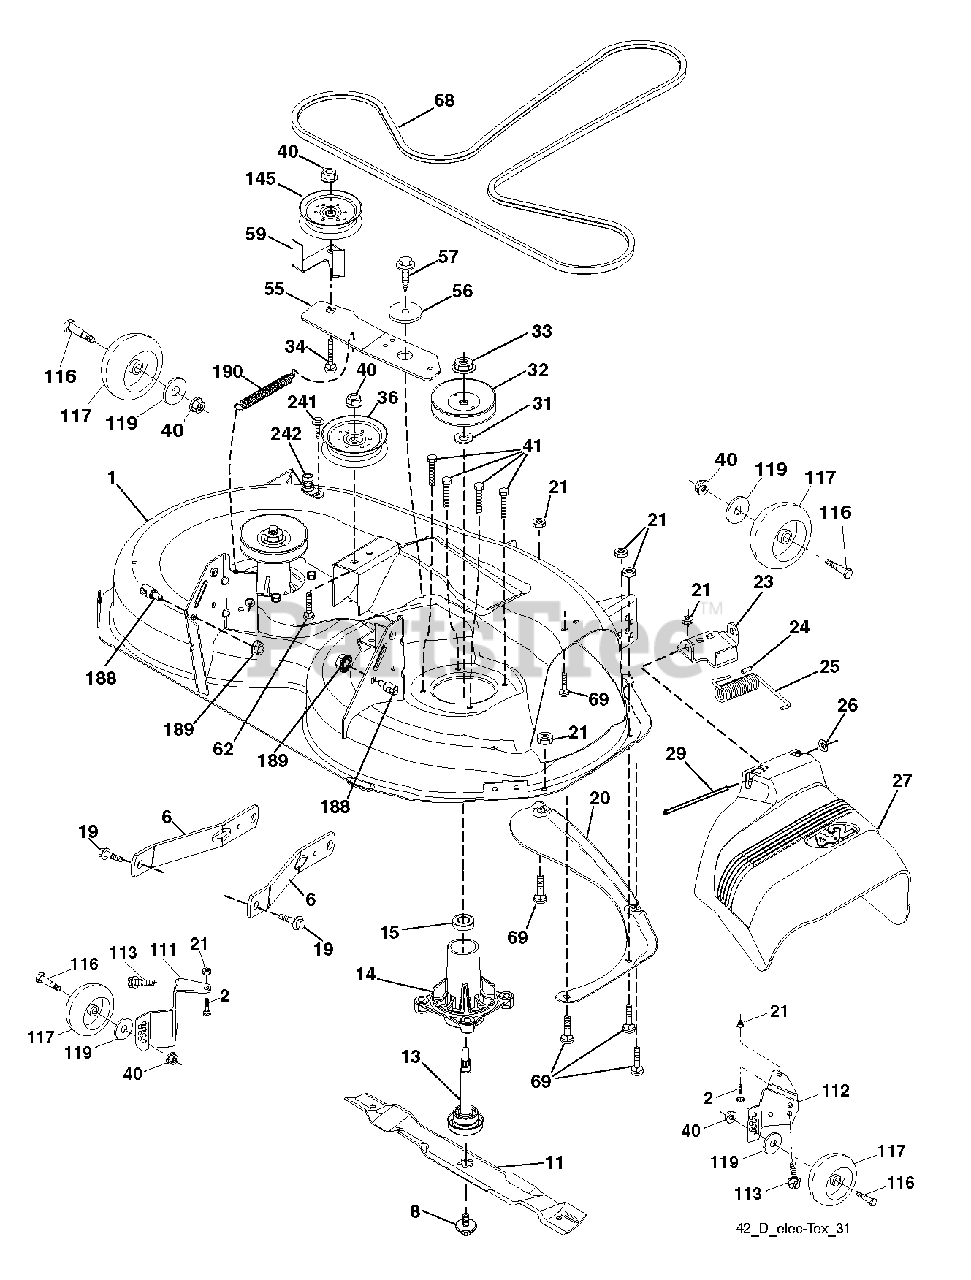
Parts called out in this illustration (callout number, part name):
1	DECK.WELDMENT.42".2GWB.BLUE
2	BOLT
6	ARM.SUSPENSION.MOWER.R
8	BOLT.WASHER.ASM.7/16-2
11	42" HI-LIFT BLADE
13	SHAFT.ASM.MDRL.N/GREASE.38
14	HOUSING.MANDREL.4PT.
15	BEARING
19	BOLT.SHOULDER
20	BAFFLE.VORTEX
21	LOCKNUT
23	BRKT.DEFLECTOR.38"2005+
24	CAP-SLEEVE LT
25	SPRING.TORSION.DEFLECT
26	NUT PUSH M
27	SHIELD.DEFLECTOR.MOWER.42"BLAC
29	ROD.HINGE
31	WASHER.SPACER.MANDREL
32	PULLEY/MANDREL
33	NUT.FLANGE.LOCK.TOP
34	BOLT.3/8-16X1.50
36	PULLEY.IDLER.2006
40	NUT LOCK FLG 3/8-16 UNC
41	BOLT.HEX.WASHR.HED.313-18X1.19
55	IDLER.ARM.42"
56	SPACER.RETAINER
57	SCREW 3/8-16X1
59	GUARD, BELT
68	BELT V SECONDARY
69	BOLT
111	BRKT.WHEEL.GAUGE.LH.42"
112	BRKT.WHEEL.GAUGE.RH.42"
113	BOLT.5/16HEX.WHS.HD
117	WHEEL.GAGE.HALF.SPOKED
119	WASHER
145	PULLEY.IDLER.48"PRIMARY
188	STUD.FASTNER.W/ANTI-ROTATE
189	NUT LOCK HEX FLANGE 5/16-18
190	SPRING.MOWER.DRIVE.ELECTRIC
241	SCREW.TT.#10-32X.5.3/8.FLANGE
242	PORT.WASHOUT
